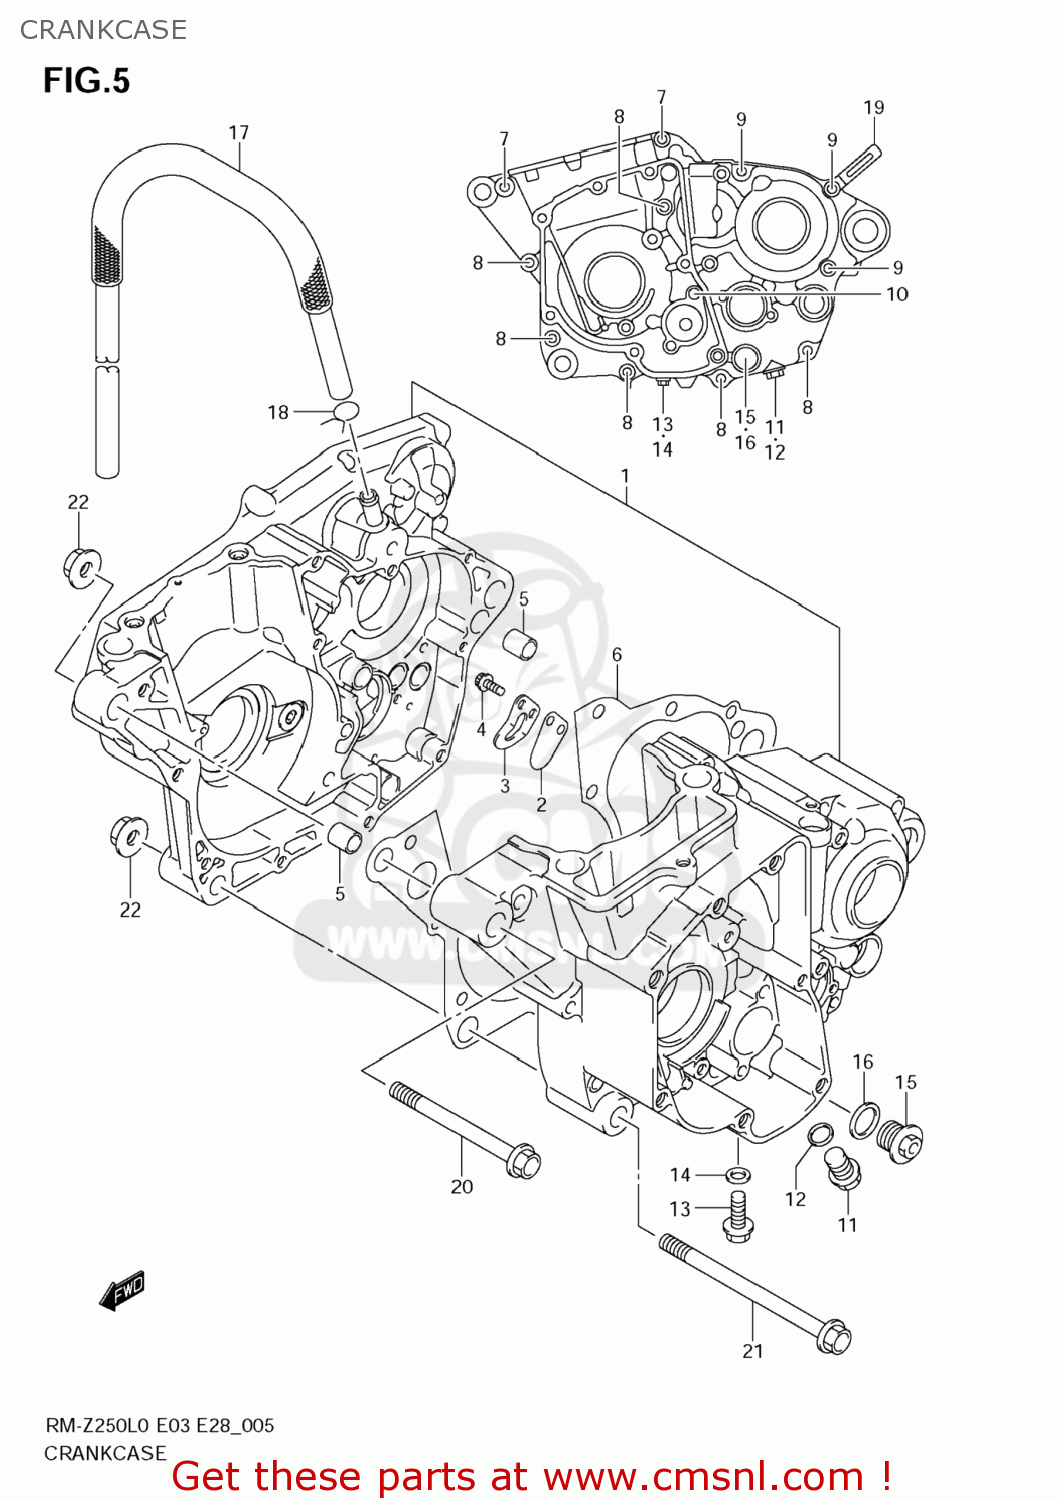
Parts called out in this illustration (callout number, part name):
1	CRANKCASE ASSY
2	VALVE,CRANKCASE REED
3	STOPPER,CRANKCASE REED VALVE
4	BOLT
5	PIN(10.4X13X18)
6	GASKET,CRANKCASE (NAS)
7	BOLT
8	BOLT
9	BOLT
10	BOLT
11	PLUG
12	GASKET(12.1X16.2X3.7) (NAS)
13	BOLT(8X20)
14	GASKET(7.8X13.5X1.2) (NAS)
15	CAP,ENG OIL STRAINER
16	GASKET(16X22X2) (NAS)
17	HOSE,BREATHER
18	CLIP
19	CLAMP(L:45)
20	BOLT(10X96)
21	BOLT(10X120)
22	NUT
